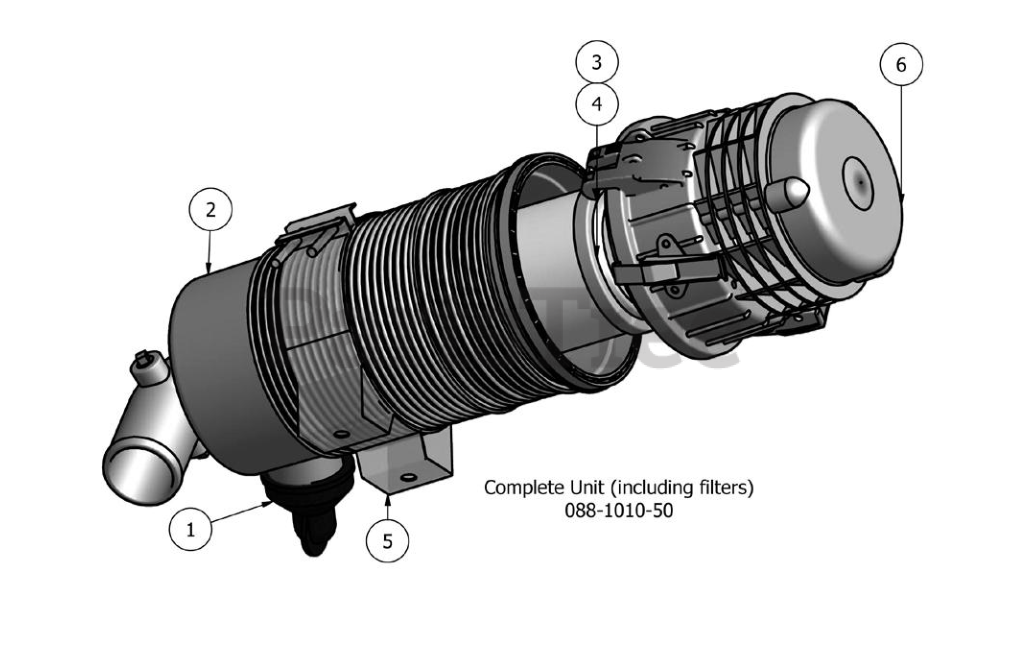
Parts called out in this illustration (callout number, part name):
1	Debris Plug
2	Canister Body
3	Inner Filter
4	Outer Filter
5	Mounting Bracket
6	Filter Cap
7	Complete Unit
